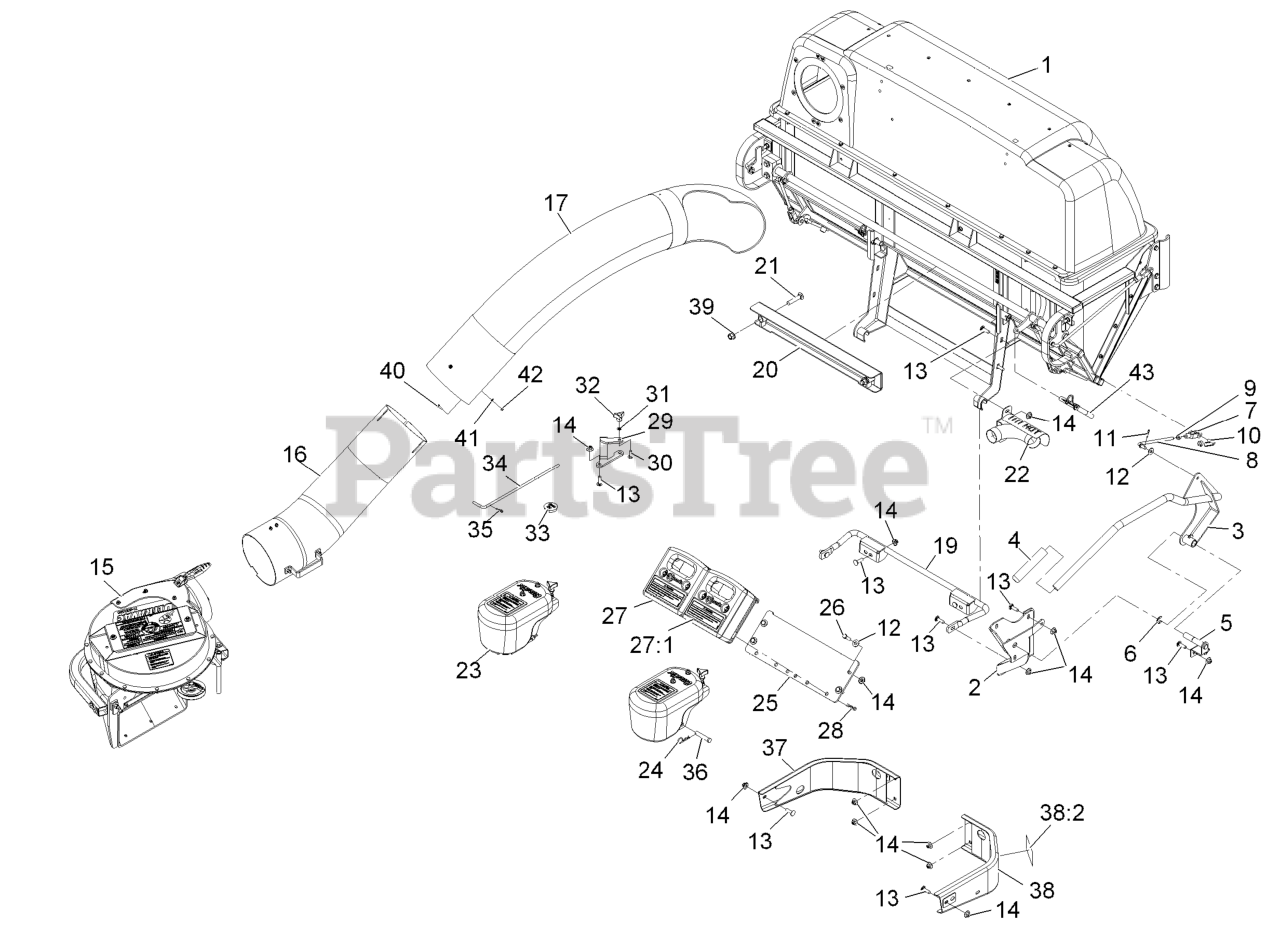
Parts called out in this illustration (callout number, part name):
1	Asm,Hopper Lg Qds
2	MOUNT-PIVOT
3	WLD,DUMP HANDLE
4	HANDLE-GRIP
5	PIN-HANDLE
7	YOKE-LINKAGE, BRAKE
8	LINK-HANDLE
9	NUT-HEX
10	PIN-SPRING, CLEVIS
11	PIN-COTTER
12	WASHER-FLAT
13	Bolt-Carriage 3/8-16 X 1 1/4
14	Nut-Nyloc 3/8-16 Flg
15	ASM, BLOWER LARGE - SVC O
16	LOWER TUBE ASM
17	TUBE-UPPER
19	MOUNT-BAGGER, LOWER
20	MOUNT-BAGGER, UPPER
21	SCREW-CARR
22	EXHAUST DIVERTER ASM
23	ASM,CASTER WEIGHT
24	PIN-COTTER
25	PLATE,WEIGHT ASM MOUNT
26	SCREW-HH
27	ASM,CAST WEIGHT
27:1	DECAL,WEIGHT
28	PIN-HAIR
29	BRACKET,BELT COVER
30	BOLT-CARR
31	RING-RETAINING, BOLT
32	KNOB-3 PRONG
33	PLUG, BLACK NYLON 1.75
34	PIN,CHUTE PIVOT
35	PIN-COTTER
36	PIN-CLEVIS
37	BUMPER-RH
38	LH BUMPER ASM
38:2	DECAL-CAUTION
39	Nut-Lock 1/2-13
40	SCREW-HWH
41	WASHER-FLAT
42	NUT-LOCK, NI
43	PIN-MOUNT, BAGGER
